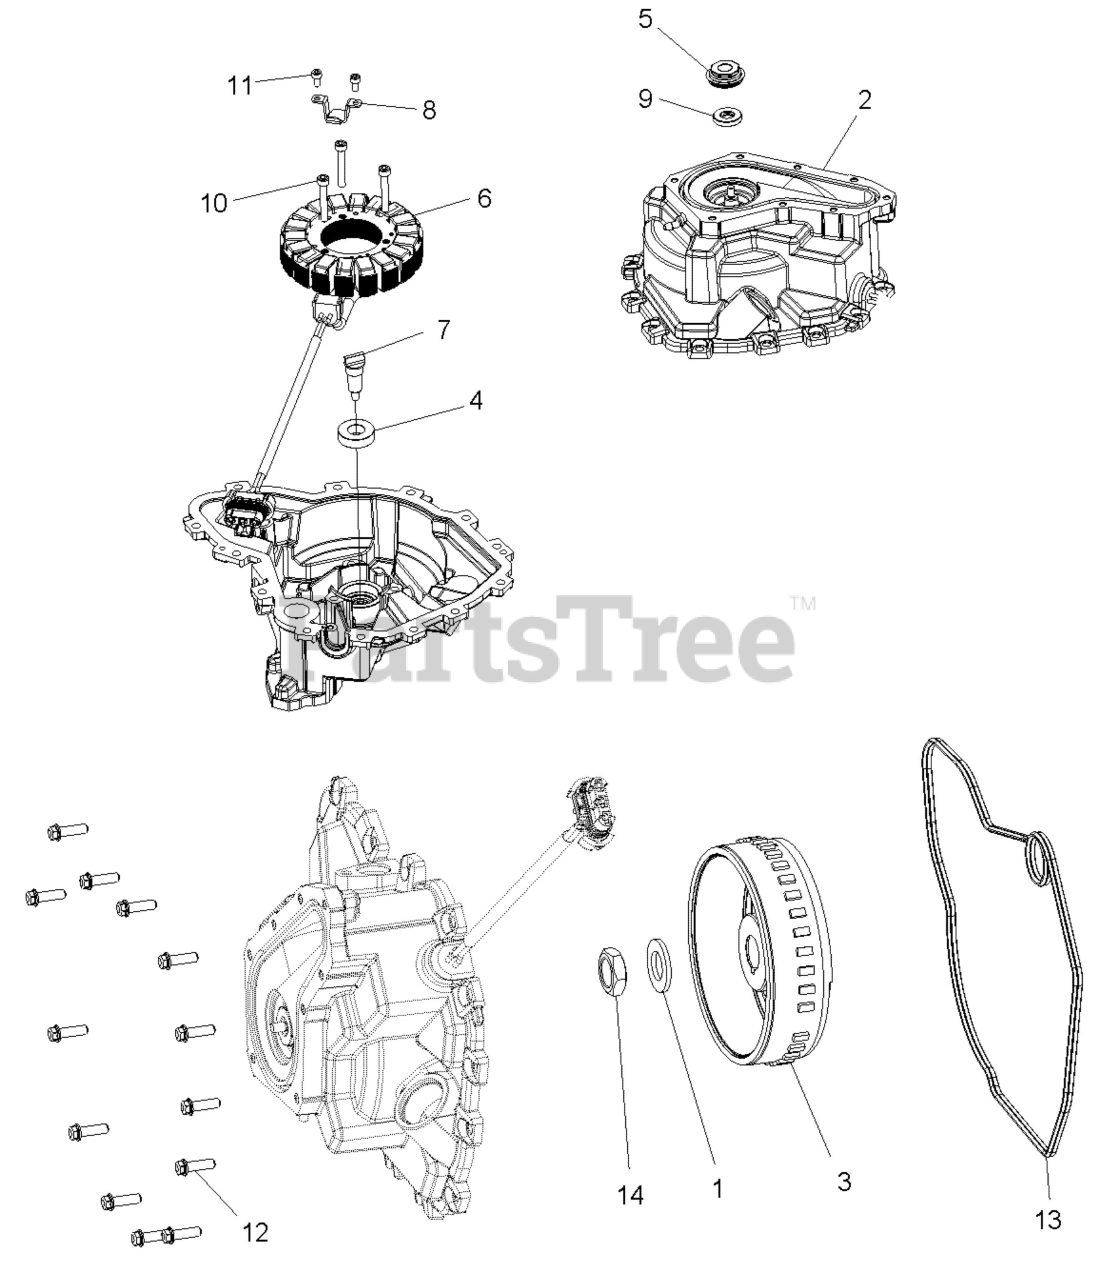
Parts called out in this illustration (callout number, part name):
2	KIT-IGNITION
3	FLYWHEEL
4	BEARING-SHAFT,WATERPUMP
5	SEAL-WATERPUMP SHAFT,WATER
6	STATOR-660W
7	SHAFT-PUMP DRIVE,G-1CYL
8	GUIDE-STATOR LEAD
9	SEAL,TYPE S,ARS
10	SCR-M6X1.0X40,HX/SOC/CP-Y/D
11	SCR-M5X0.8X10 SOC/CP-D
12	SCR-M6X20,HXFLG,0600214
13	GASKET-STATOR COVER
14	NUT-HEX,M18X1.5 4 JAM,RH
